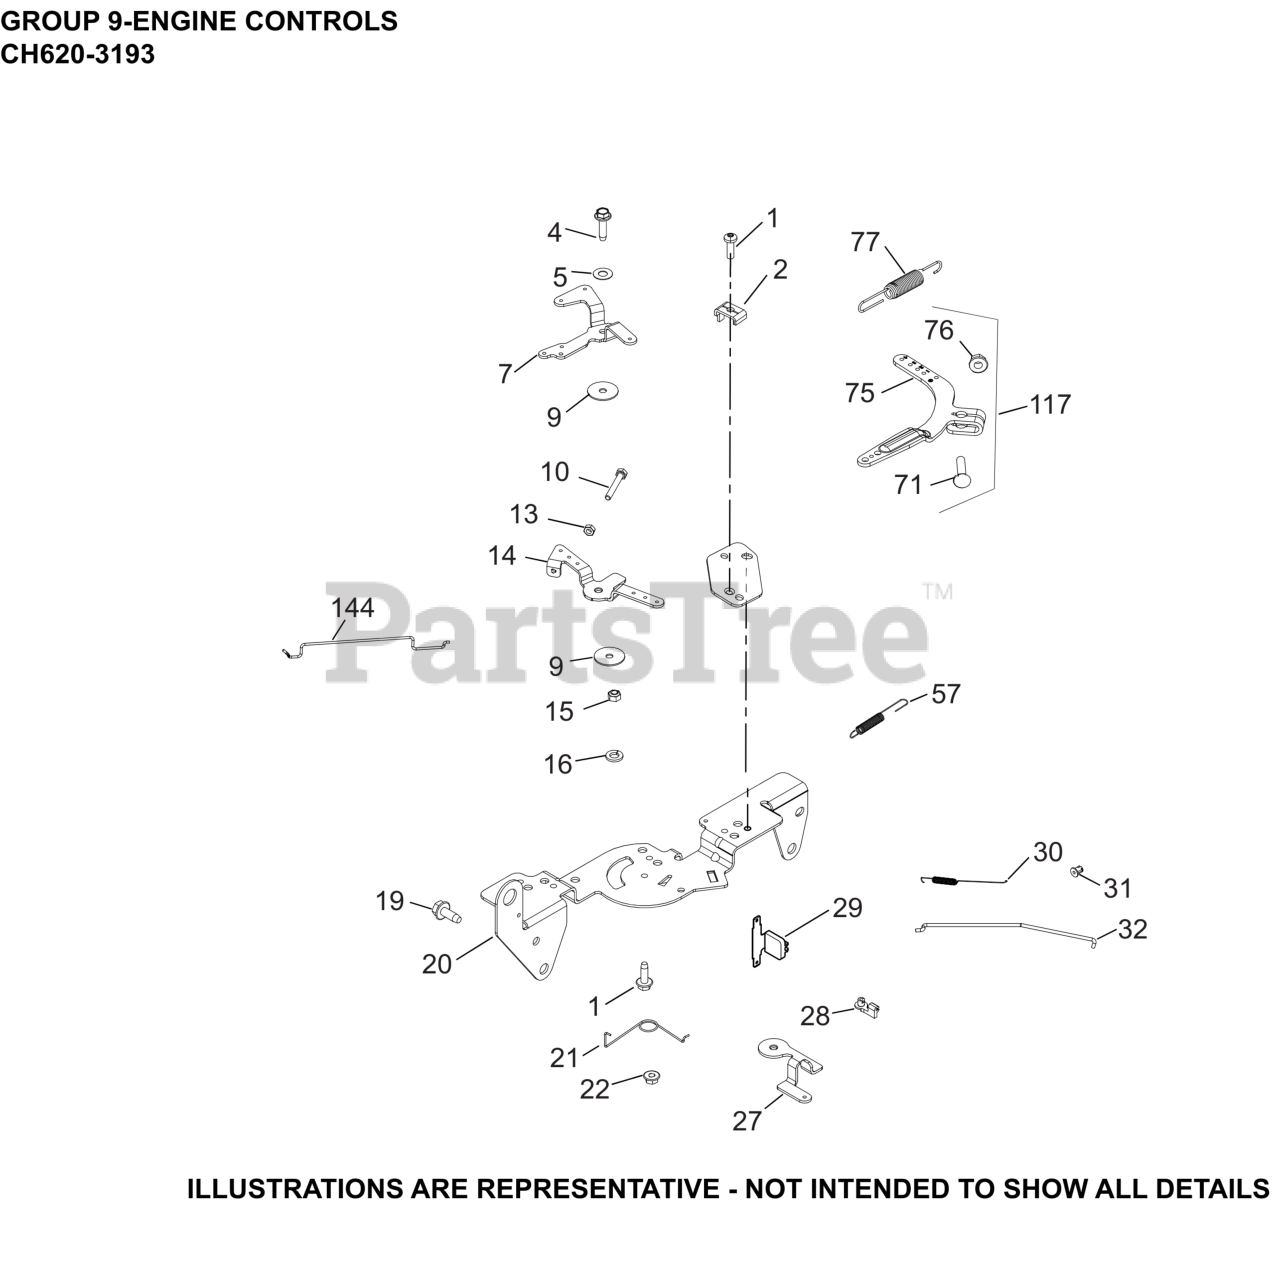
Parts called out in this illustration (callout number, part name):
1	SCREW, THREAD FORMING
2	CLAMP, CABLE CABLE
4	SCREW, THD FRM-USE 25 086 473-S
5	WASHER, SPRING 1/4"
7	LEVER, CHOKE
9	WASHER, FLAT 5.5 MM
10	SCREW, CAP M4X.7X30
13	NUT, M4X0.7
14	LEVER, THROTTLE CONTROL
15	NUT, FLG M5X.8
16	WASHER, SPRING LOCK 1/4"
19	SCREW, THREAD FORMING
20	BRACKET, CONTROL
21	SPRING, CHOKE RETURN
22	NUT, LOCK M5X.8
27	LEVER, THROTTLE ACTUATOR
28	BUSHING, THROTTLE LINKAGE
30	SPRING, LINKAGE
31	BUSHING, LINKAGE RETAINING
32	LINKAGE, THROTTLE
57	SPRING, THROTTLE LIMITER
71	BOLT, RD HD SQ NECK M6X1.0X25
75	LEVER, GOVERNOR - (#2409069S)
76	NUT, FLG M6X1.0
77	SPRING, GOVERNOR (BLUE)
117	LEVER, GOVERNOR ASSEMBLY
144	LINKAGE, CHOKE
